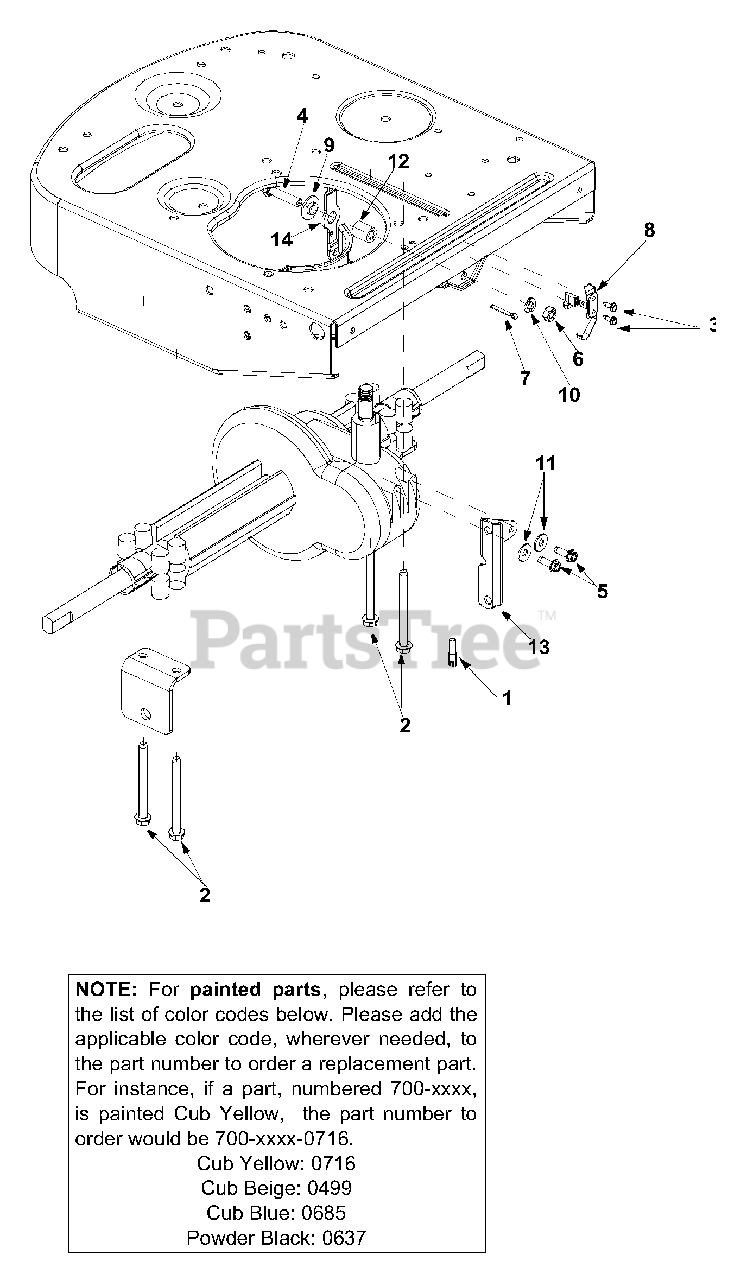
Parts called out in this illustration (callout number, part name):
1	Harness Assembly Adapter
2	Hex TT Screw 5/16-18 x 3.50
3	Hex Washer Head Self-Tap. Screw
4	Hex Screw 5/16-18 x 1.5 Gr. 5
5	Thd. Forming Scr. 1/4-20x .75
6	Hex Nut 5/16-18
7	Cotter Pin
8	Insulator Nut Plate
9	Shoulder Bushing
10	Lock Washer 5/16
11	Flat Washer
12	Spacer
13	Transaxle Bracket
14	Shift Lever
